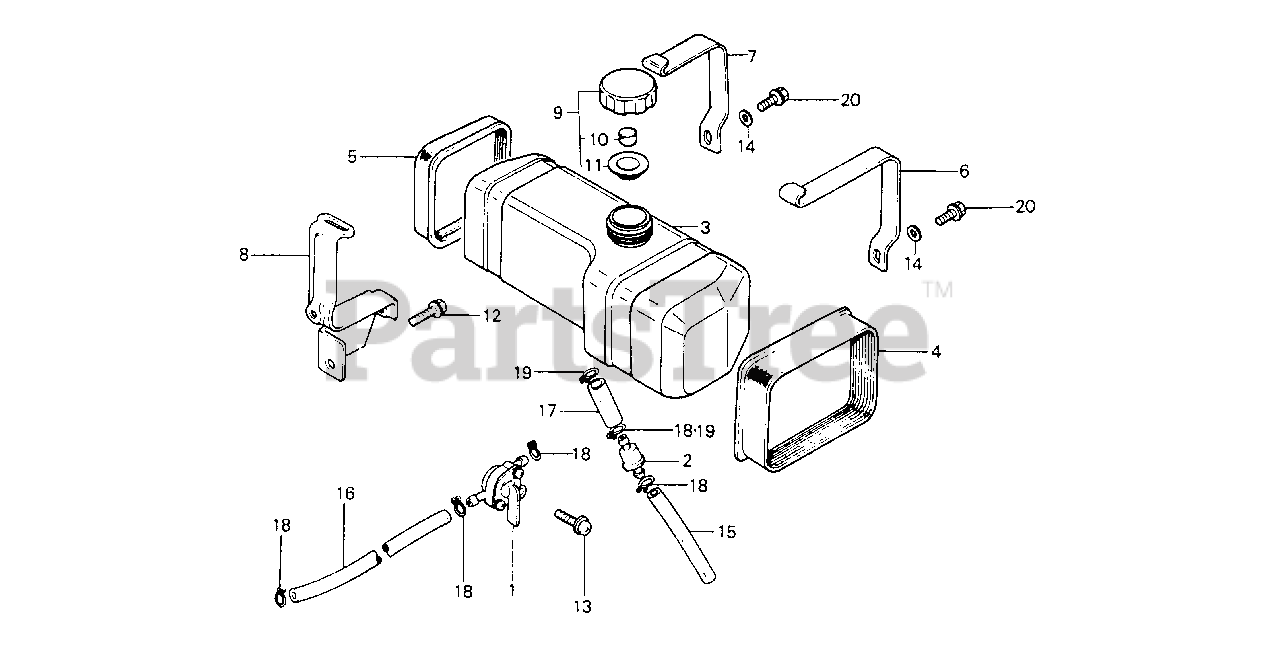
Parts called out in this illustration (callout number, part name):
1	PETCOCK ASSY.
2	FILTER, FUEL
3	TANK, FUEL (NOT AVAILABLE)
4	RUBBER A, FUEL TANK MOUNTING
5	RUBBER B, FUEL TANK MOUNTING
6	BAND A, TANK MOUNTING
7	BAND B, TANK MOUNTING
8	STAY B, TANK
9	CAP ASSY., FUEL TANK
9	CAP ASSY., FUEL TANK Use from Engine SN 2010636.
10	SPONGE, FUEL CAP BREATHER
11	GASKET, FUEL CAP
11	GASKET, FUEL CAP Use from Engine SN 2007016.
12	BOLT, FLANGE (6X12) (CT200)
13	SCREW-WASHER (5X12)
14	WASHER, PLAIN (6MM)
15	BULK HOSE, FUEL (4.5X3000) (Honda Code 5137104). (4.5X140)
16	BULK HOSE, FUEL (4.5X3000) (Honda Code 5137104). (4.5X140)
17	TUBE, FUEL
17	BULK HOSE, FUEL (5.5X3000) (Honda Code 5338587). (5.5X150)
18	CLIP, TUBE (B8)
19	CLIP, TUBE (B10)
20	BOLT, FLANGE (6X12) Use from Engine SN 2086984.
